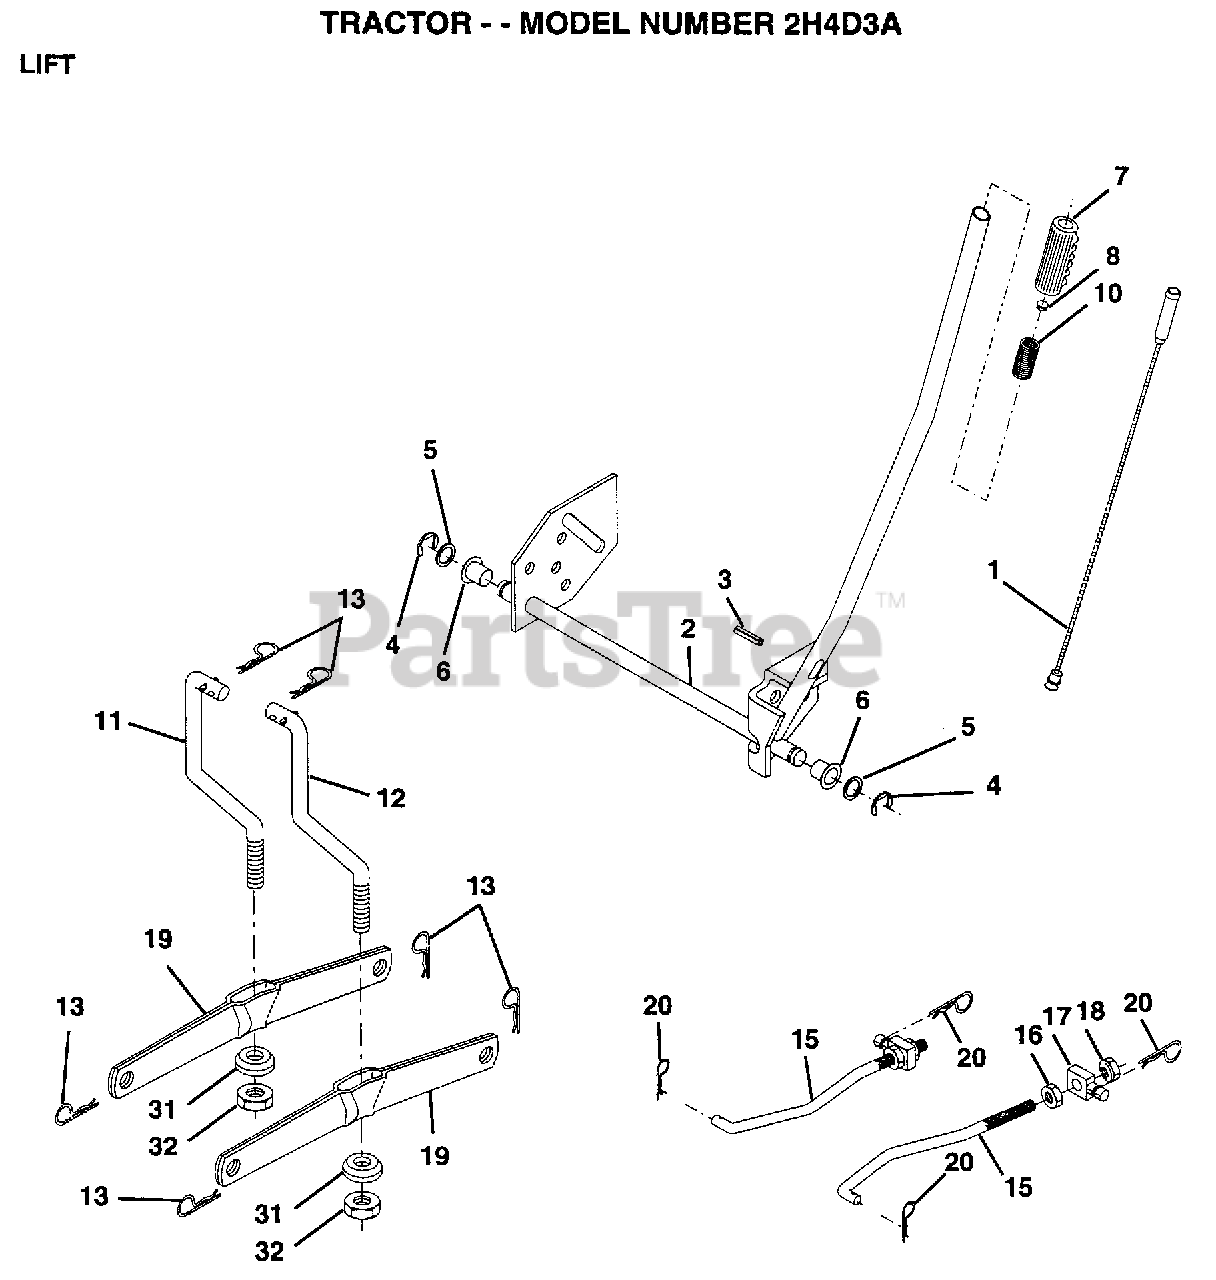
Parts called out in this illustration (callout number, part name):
1	WIRE.ASM.INNER
2	SHAFT.ASM.LIFT.RH
3	PIN GROOVE
5	WASHER
6	NYLON BEARING
7	GRIP
15	LINK.FRONT
16	NUT
17	TRUNION
18	NUT.LK.W/WSH.1/2.
19	ARM SUSP REAR
20	RETAINER.SPRING
31	BEARING PVT LH
32	NUT.CROWNLOCK.3/8
